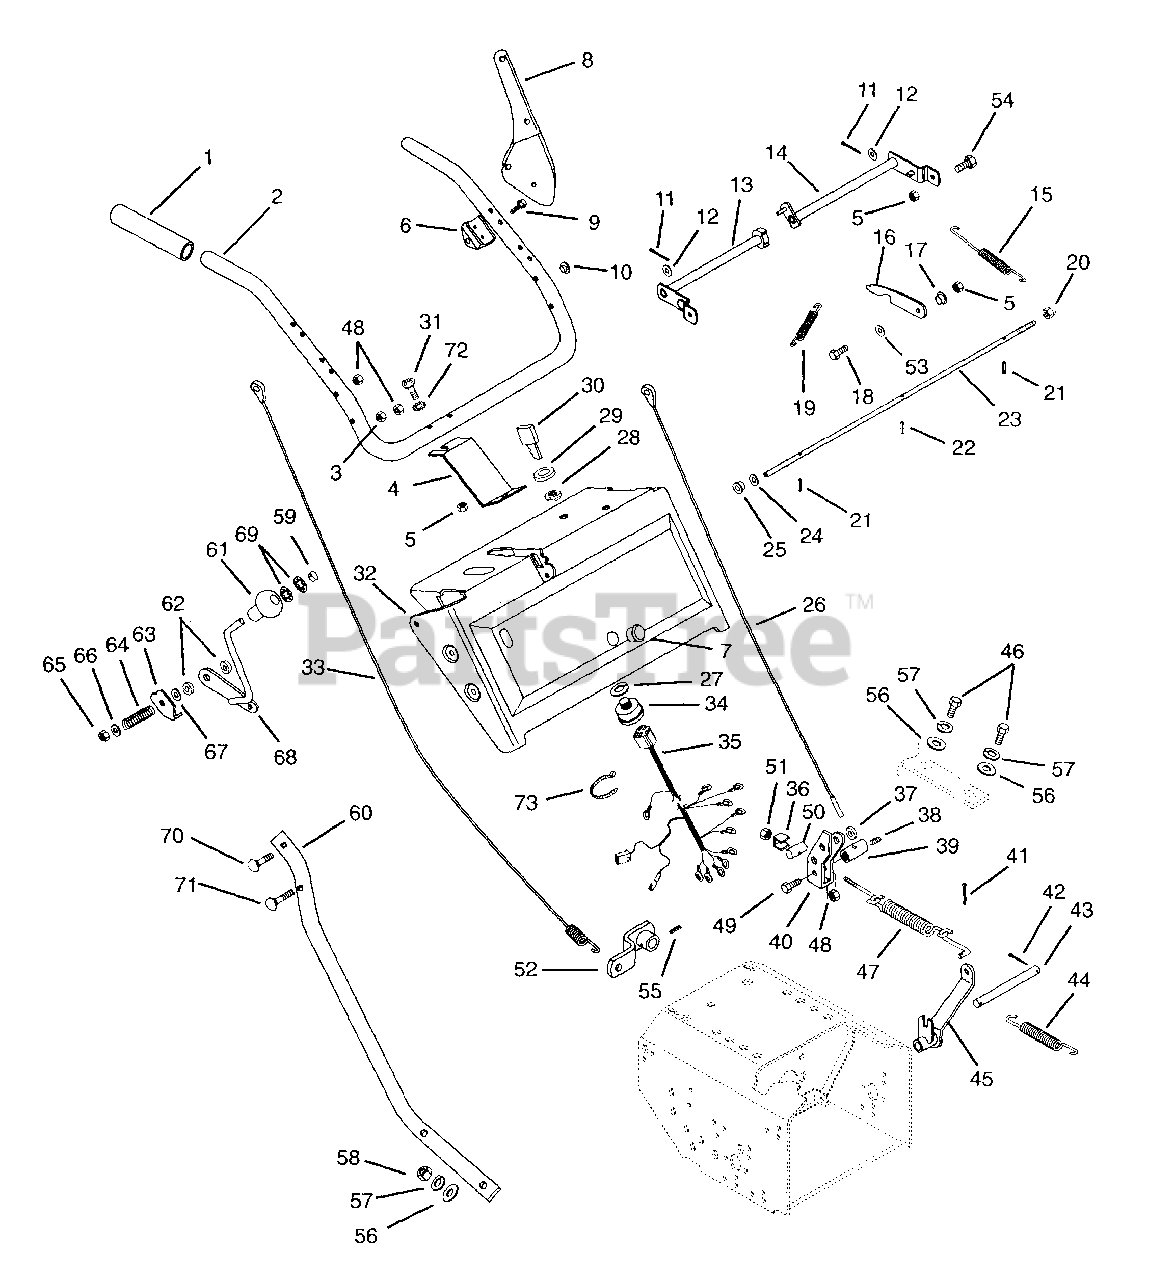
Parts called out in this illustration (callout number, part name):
1	HANDLE GRIP
2	UPPER HANDLEBAR
3	@NUT-SPNLK-FLG .312-18 YWZC
4	BRACKET, DEFLECTOR CABLE
5	@NUT-LK-CTR .25-20 YWZC
6	HANDLE PIVOT
7	SNAP BUSHING
8	CLUTCH LEVER - COATED
9	SCR-TAP 12-24X1.50 CROVH YZ BT
11	@PIN-CTR .09X.50 EXTPRSQCT YWZ
12	@WSHR-FL-STL.281X.62X.065 YWZC
13	LEVER,RH
14	LEVER, L.H.
15	SG-TENS .051X.50X5.12 WLD 10.4
16	ARM, LATCH
17	BSHG-FLG .265X.437X.329X1.00
18	@BLT-HEX .25-20X.75 GR5 YWZC
19	SG-TENS .048X.44X1.75 WLD 9
20	NUT-CROWN .312-18 YWZC
21	PIN-ROLL .156X.75
22	PIN-ROLL .125X1.00
24	WSHR-FL-STL .323X.625X.062 YWZ
25	BSHG-FLG .325X.465X.333X.685
26	CABLE, TRACTION CLUTCH
27	WSHR-LK-INT .625X.045 YWZC
28	NUT-PANEL .625-32 GRECO
29	CAP - IGNITION SWITCH
30	KEY -W/CAP
31	SCR-MCH .25-20X1.5 PH OVL HD Y
32	PANEL W/DECAL
33	CABLE, BLOWER CLUTCH
34	SWITCH ASSEMBLY
35	12 V HARNESS
36	ADAPTER SPACER
37	SPACER 1.00 X .64 X .38
38	SCR-SET .32-18X.38 SKHCUPNL OH
39	ROD ADAPTER
40	CLUTCH ENGAGEMENT YOKE
41	@PIN-CTR .09X.50 EXTPRSQCT YWZ
42	@PIN-CTR .09X1.00 EXTPRSQCT YZ
43	ROD, FORK PIVOT
44	SG-TENS .080X.73X3.06 WLD 20
45	FORK, CLUTCH
46	@BLT-HEX .38-16X1.00 GR5 YWZC
47	SPRING ASSEMBLY
48	@NUT-LK-CTR .31-18 YWZC
49	@BLT-HEX .31-18X.75 GR5 YWZC
50	ADAPTER
51	@NUT-LK-NYL .312-18 YWZC
52	LEVER, CLUTCH
53	WSHR-FL-STL .505X.875X.024 YWZ
54	@BLT-HEX .25-20X.50 GR5 YWZC
55	PIN-ROLL .156X.88
56	@WSHR-FL-STL.438X1.00X.083 YWZ
57	WSHR-LK .375X.115 HVY YWZC
58	@NUT-HEX .38-16 YWZC
59	HOLE PLUG
60	HANDLEBAR, L.H. LOWER
60	HANDLEBAR, R.H. LOWER
61	KNOB
62	HANDLEBAR, R.H. LOWER
63	PRESSURE FLANGE
64	SG-COMP .187X.56X1.62
65	@NUT-LK-CTR .38-16 YWZC
66	@WSHR-FL-STL.406X.812X.065 YWZ
67	SPACER .406X.620X.125
68	LEVER-DEFLECTOR
69	RG-RTNG-EXT .375X.010
70	@BLT-RDHDSQNK .31-18X1.75 G5YZ
71	BLT-RDHDSQSHNK.31-18X2.75G2YWZ
72	WSHR-LK-EXT .250 TTH CNTRSNK
73	CABLE TIE LG 5-1/2
